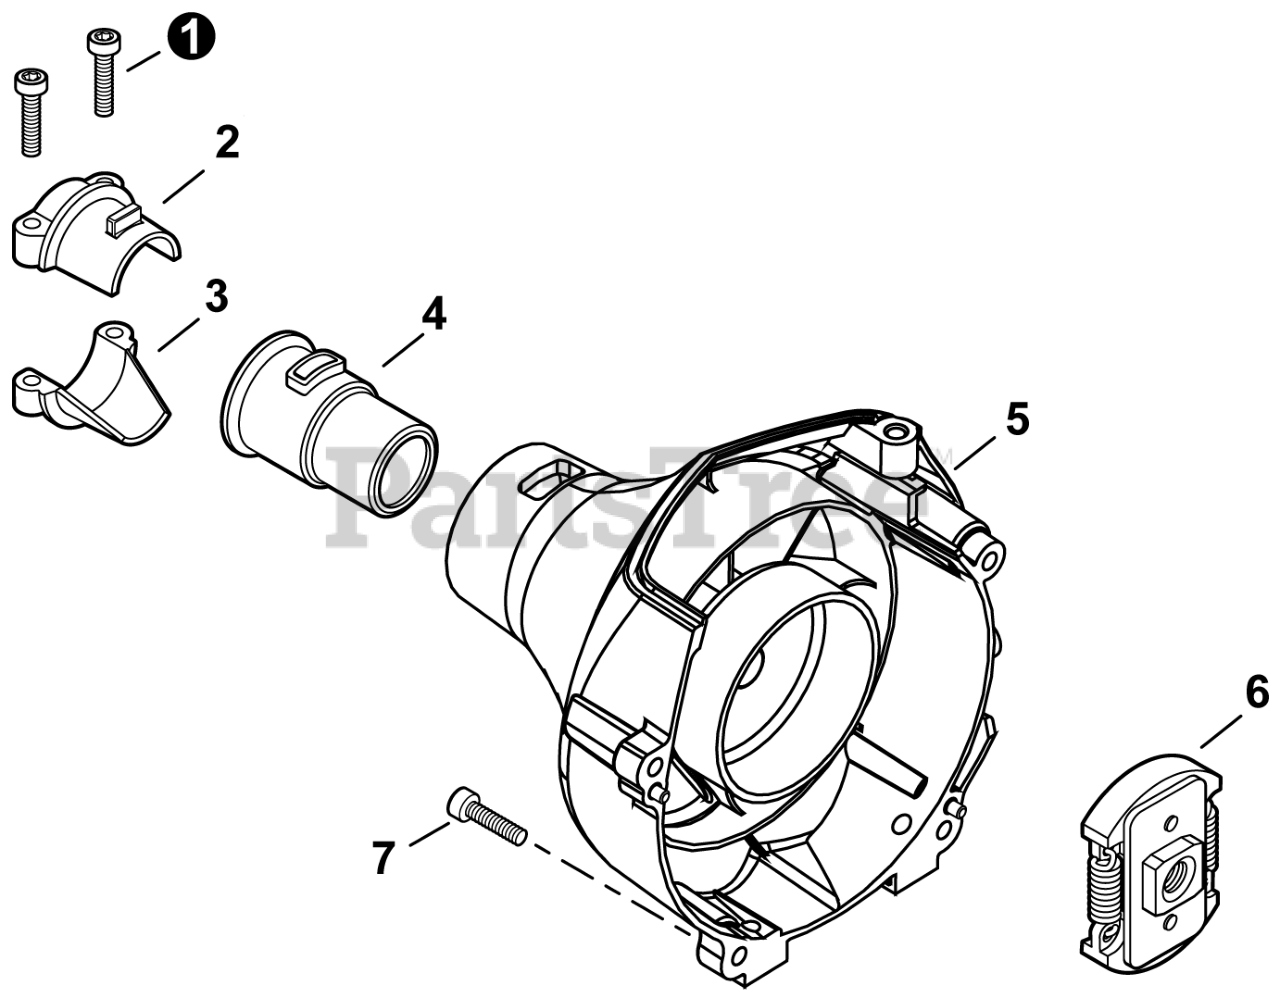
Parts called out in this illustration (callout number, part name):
1	BOLT, TORX 5x20
2	HOLDER, MAIN PIPE - UPPER
3	HOLDER, MAIN PIPE - LOWER
4	CUSHION, MAIN PIPE
5	COVER ASSY, FAN
6	CLUTCH ASSY
7	BOLT, TORX 4x16
